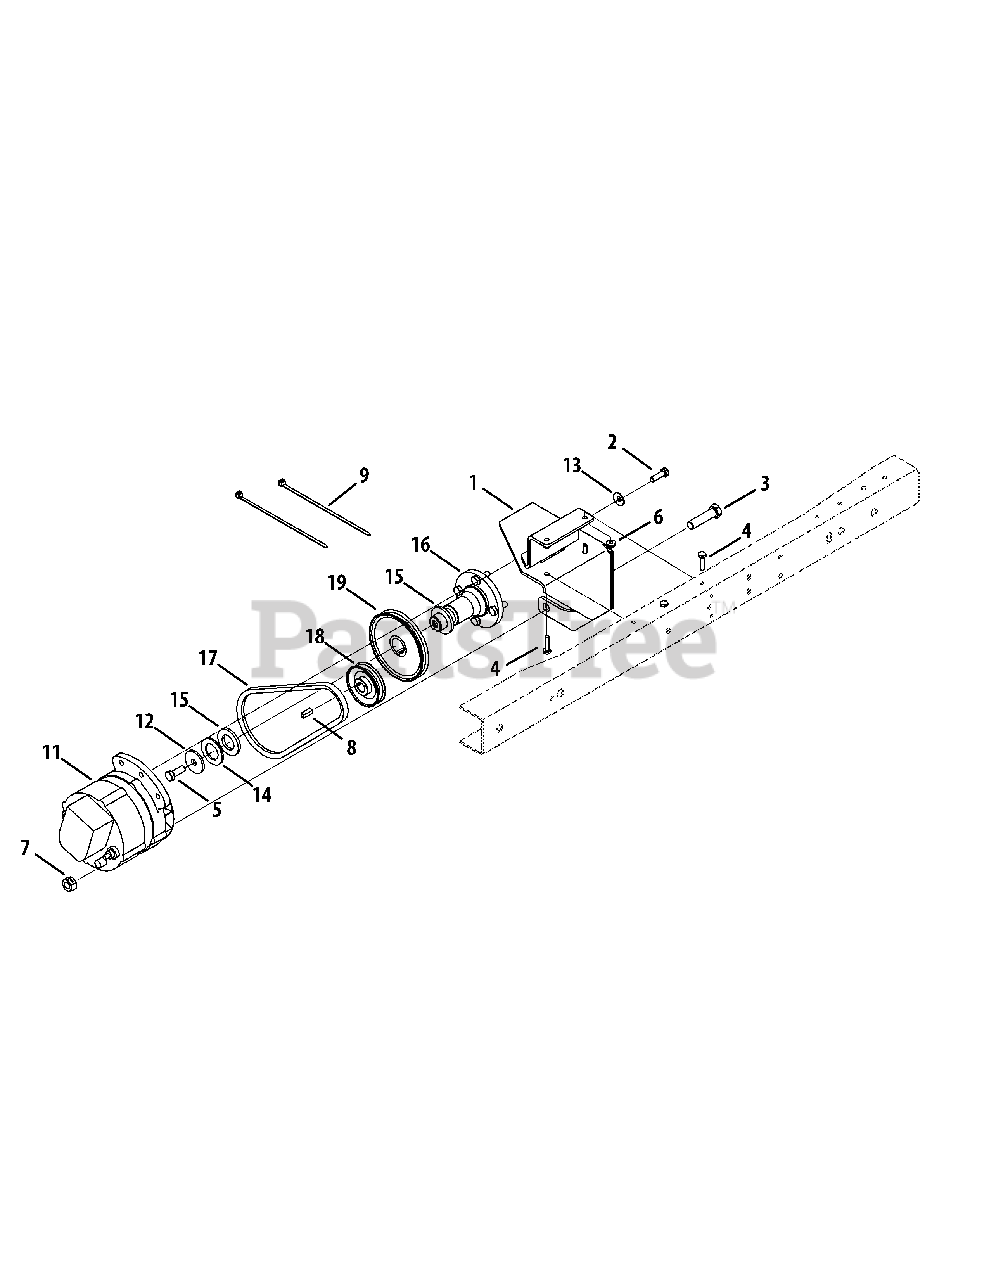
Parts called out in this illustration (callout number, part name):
1	Support Assembly, Altnr., Koh
2	Hex Head Screw, 5/16-18 x 1.00
3	Hex Head Screw, 1/2-13 x 2.00
4	Hex Head Screw, 1/4-20 x 1.00
5	Hex Head Screw, 3/8-16 x 1.00
6	Nut, Flange Lock, 1/4-20
7	Nut, Hex Lock., 1/2-13
8	Square, Key, 1/4 x .75
9	Tie, Cable
11	Alternator, Aux., 65 Amp
12	Washer, Flat, .390 x 1.5 x .134
13	Washer, Bell, .340 x .872 x .060
14	Washer, Flat, 1.00 x 1.75 x .107
15	Washer, Flat, 1.01 x 1.75 x .172
16	Shaft, Kohl., Front, Drive
17	Belt, 3/8 x 24.68
18	Pulley, 2.65 OD, 3L
19	Pulley, 4.5 OD, 1" Bore
